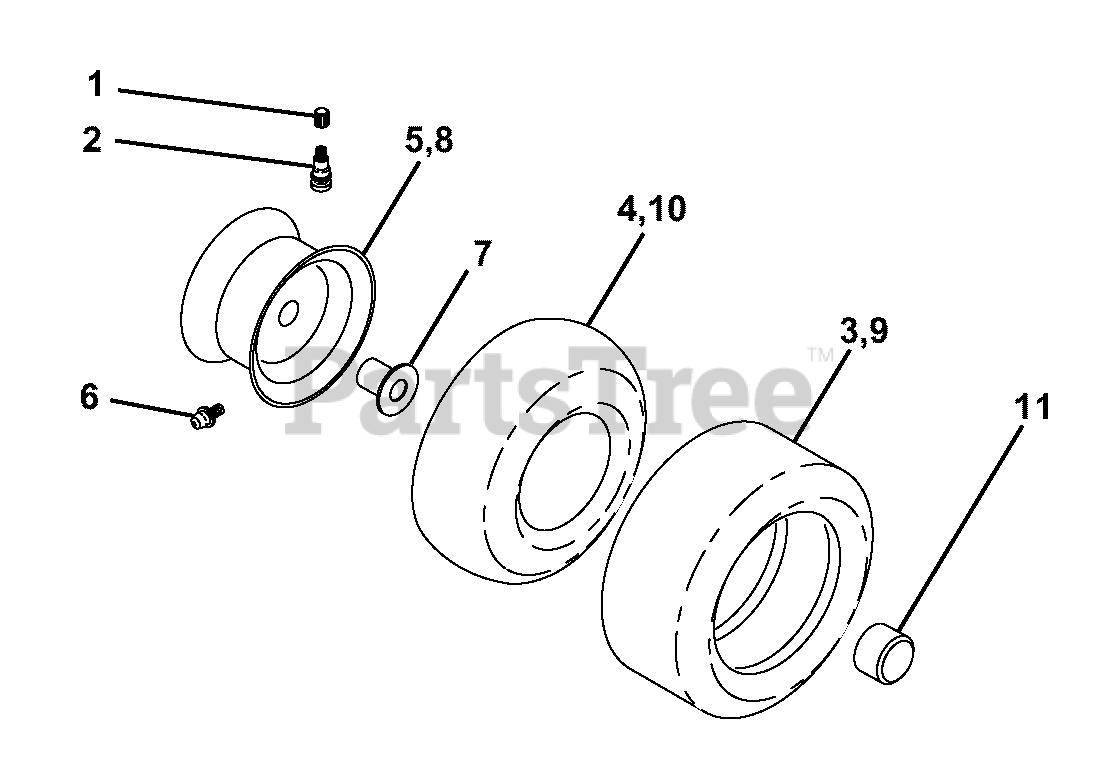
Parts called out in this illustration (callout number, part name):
1	Cap Valve Tire
2	Stem Valve
3	Tire F T 15 X 6 0 - 6 Service M
4	Tube Front
5	Rim Asm 6" front Service
6	Fitting Grease
7	Bearing Flange
8	Rim Asm 8"rear Service
9	Tire R T 20x10-8 C Service M
10	Tube Rear
11	Cap Axle Blk 1 50 X 1 00
